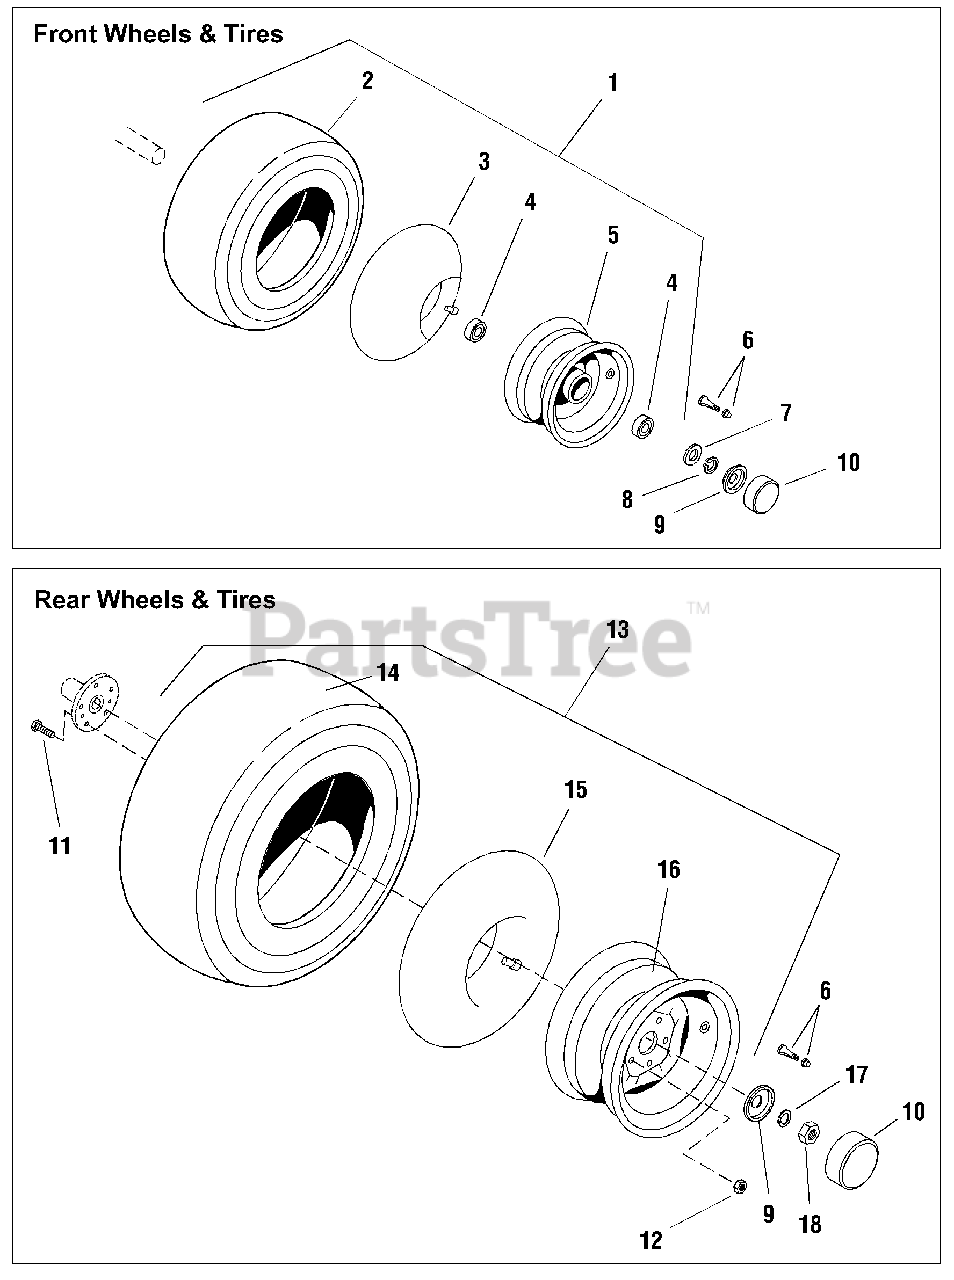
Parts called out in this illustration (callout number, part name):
1	WHEEL & TIRE ASSEMBLY, Front, 18 x 8.5 - 8 Tires
2	TIRE, Standard, Front, 18 x 8.5 - 8
2	TIRE, Optional 4-Ply, Front, 18 x 8.5 - 8 (For tractors equipped with front end loaders)
3	TUBE, Inner, Front
4	BEARING, Ball
5	WHEEL ASSEMBLY, Front.
6	VALVE STEM & CAP
7	WASHER, 1.0
8	RING, Retainer
9	RETAINER, Cap
11	STUD, Wheel, 7/16-20 x 1.23
12	NUT, Lug Bolt, 7/16-20
13	WHEEL & TIRE ASSEMBLY, Rear, 26 x 12.00-12 Tires
14	TIRE, Optional with AG-Tread, Large Rear, 26 x 12 - 12
14	TIRE, Standard, Rear, 26 x 12.00-12
15	TUBE, Inner, Rear, for all 26 x 12.00 - 12 tire applications
16	WHEEL ASSEMBLY, Rear, for 26 x 12.00-12 Tires
17	RETAINER, Spec. Washer
18	NUT, Hex Jam, 1 x 14
